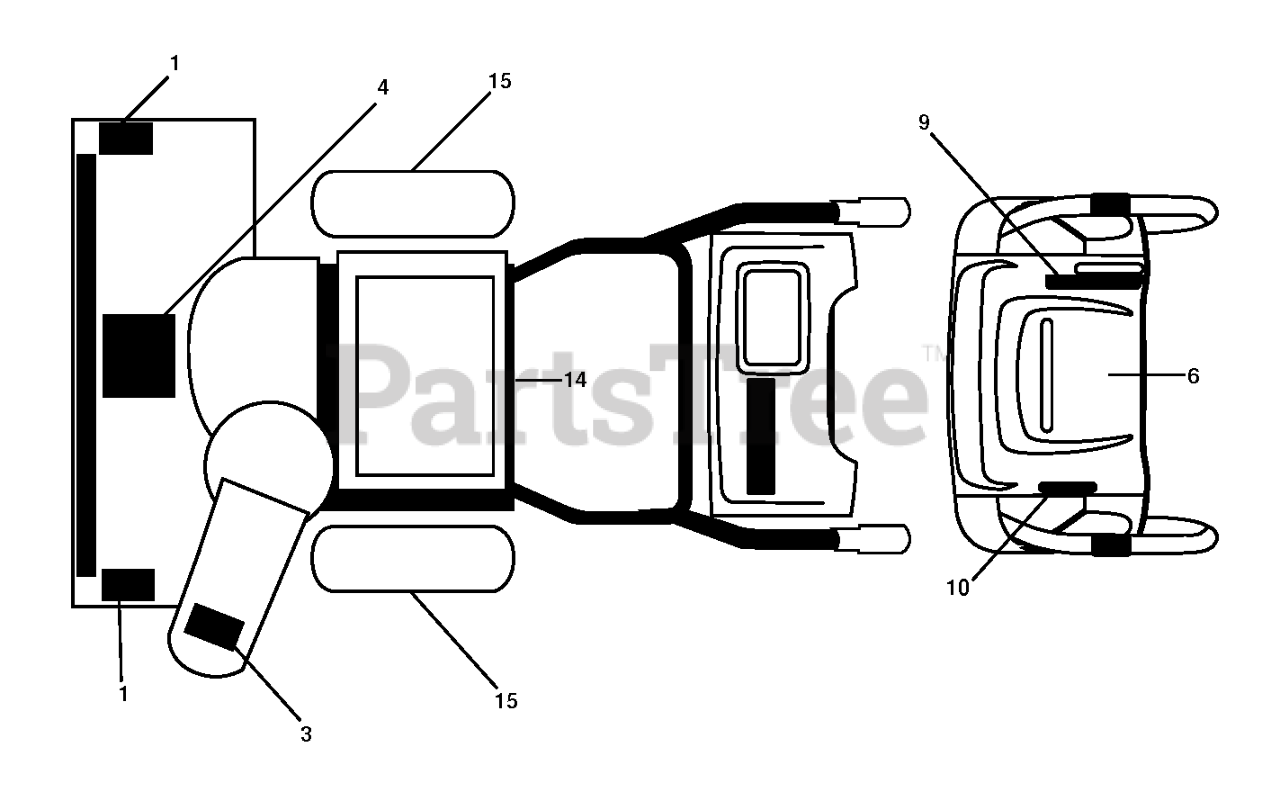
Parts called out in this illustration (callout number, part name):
1	DECAL.AUGER.SAFETY.
3	DECAL.CHUTE.SAFETY.
4	DECAL.AUGER."
9	DECAL.CONS.RT.SPD/LEV/PWRST.
10	DECAL.CONS.LT.SPD/LEV/PWRST.
14	DECAL.FENDER
15	DECAL.BELT.GUARD.
